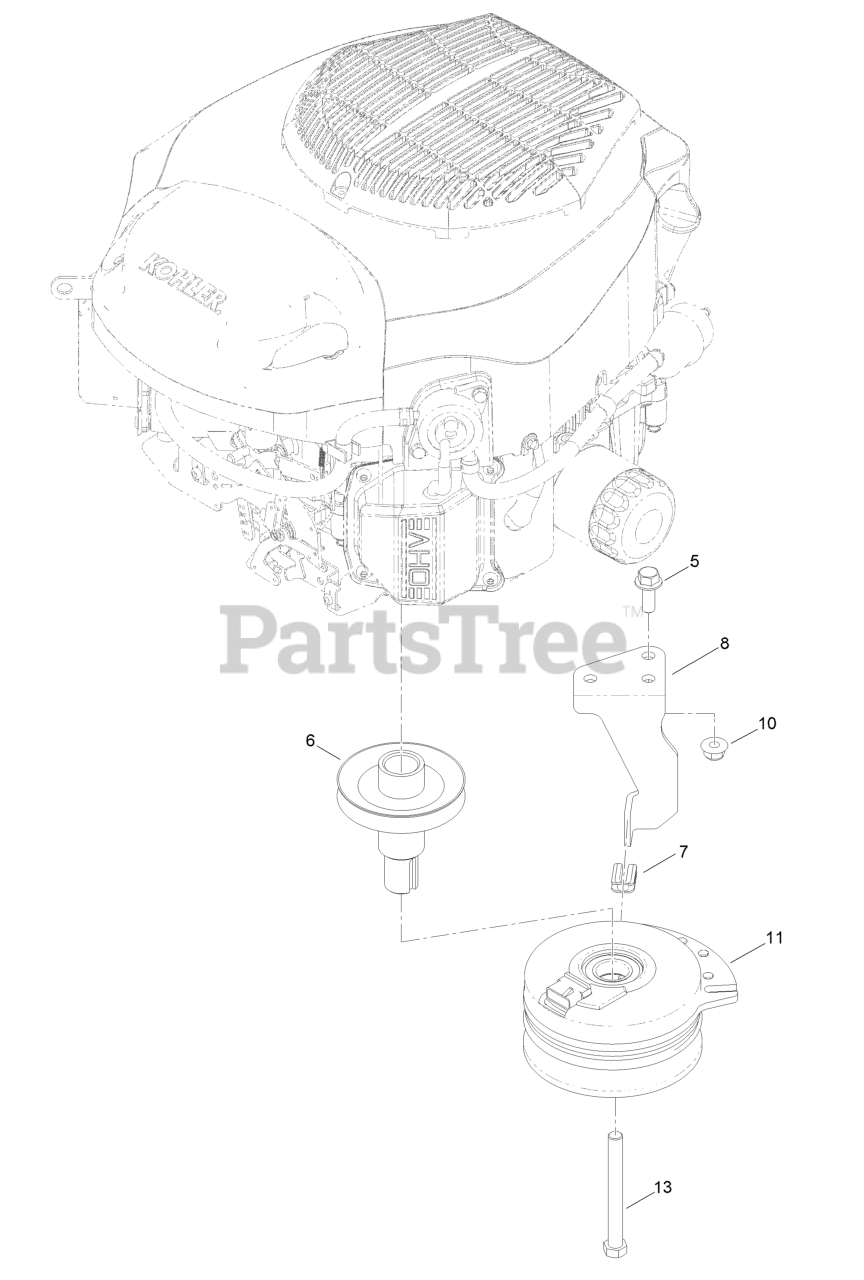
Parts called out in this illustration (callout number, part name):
5	SCREW-HHF 3/8-16 X 1
6	PULLEY-ENGINE
7	ISOLATOR-CLUTCH
8	STOP-CLUTCH (NARROW)
10	NUT-HF, NI
11	CLUTCH-ELECTRIC
13	PIN-ROLL, SLOTTED
